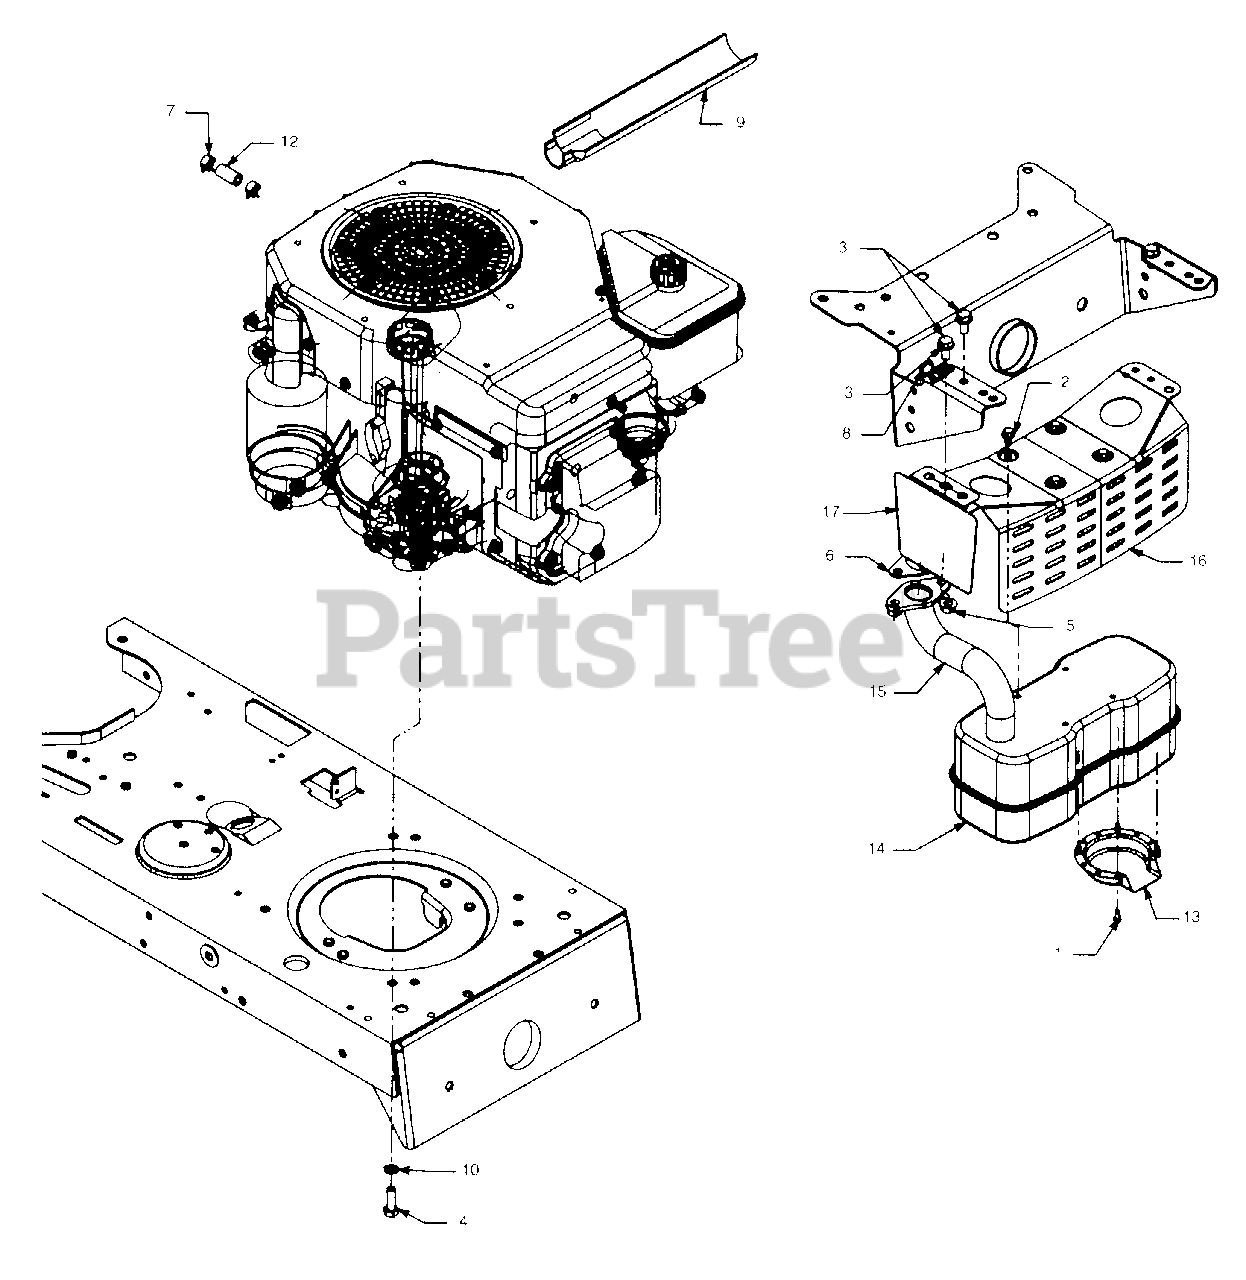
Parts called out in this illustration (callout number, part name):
1	Hex Tap Scr. #8-32 x .38" Lg.
3	Hex Wash. TT-Tap Scr. 5/16-18 x .62" Lg.
4	Hex Bolt M8 x 1.25
5	Hex Flange Nut M8 Thd.
6	Exhaust Gasket
7	Hose Clamp
8	Clamp
9	Oil Drain Sleeve
10	External L-Wash. 5/16" I.D.
12	Fuel Line 12" Lg.
13	Muffler Deflector
14	Muffler
15	Exhaust Pipe
17	Shield Bracket.
